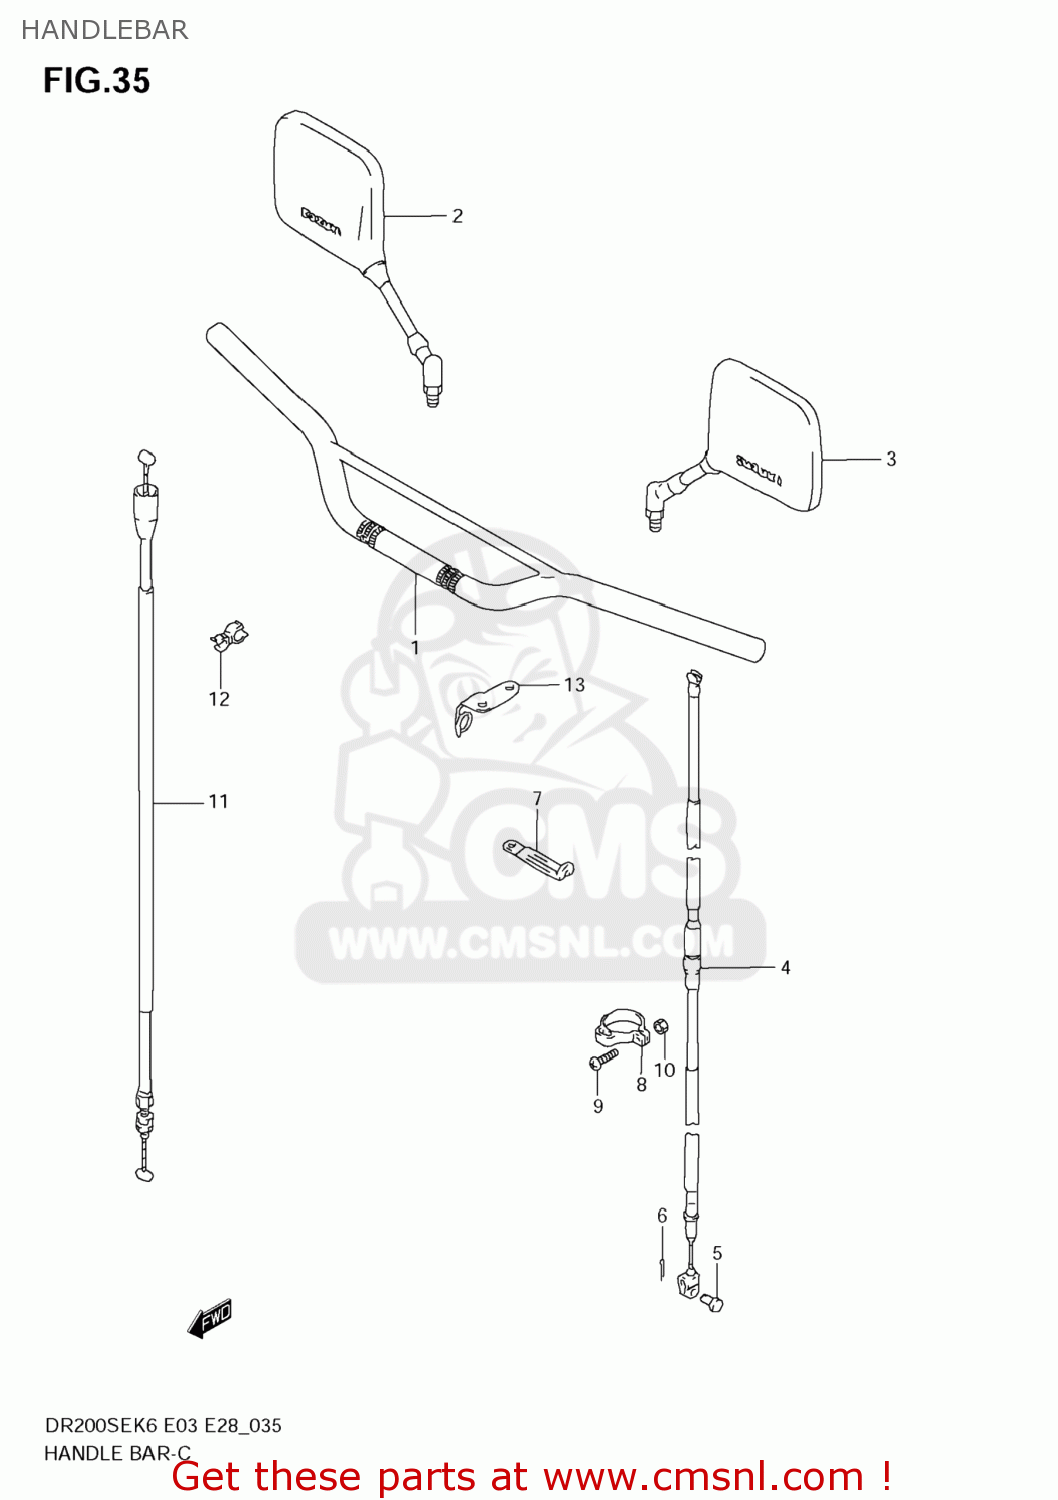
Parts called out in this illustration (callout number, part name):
1	HANDLEBAR(BLACK)
2	MIRROR ASSY,RR VIEW,R
3	MIRROR ASSY,RR VIEW,L
4	CABLE ASSY,CLUTCH
5	PIN(L:13)
6	PIN
7	CLAMP(L:235)
8	CLAMP,CLUTCH CABLE
9	SCREW
10	NUT
11	CABLE ASSY,THROTTLE
12	CLAMP
13	GUIDE,CABLE
